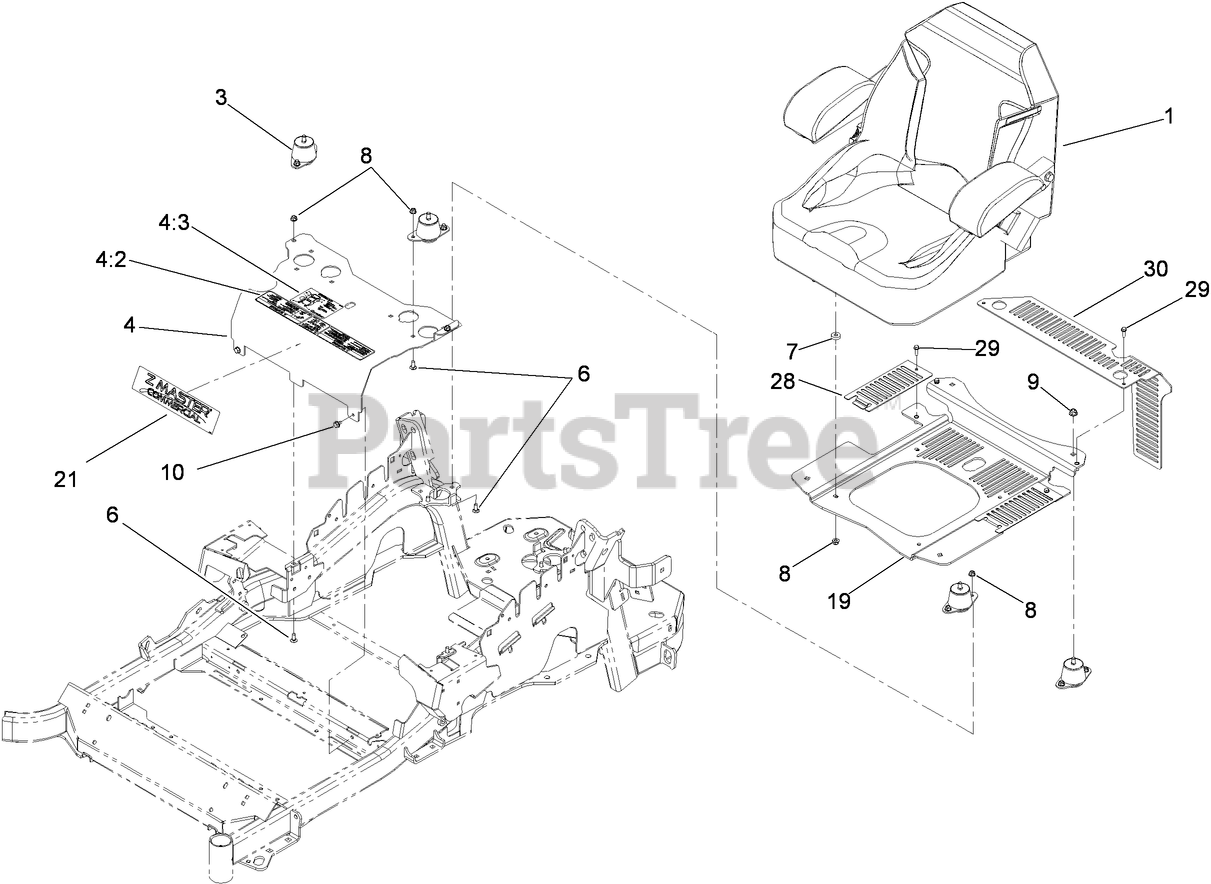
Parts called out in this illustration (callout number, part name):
1	SEAT-STANDARD
3	ISOLATOR-SEAT
4	MOUNT-SEAT
4:2	DECAL-CONSOLE
4:3	DECAL-SERVICE AID
6	SCREW-CARR
7	SPACER-PIN, MOUNTING
8	NUT-HF, NI
9	NUT-HF, NI
10	SCREW
19	SEAT BASE ASM
29	SCREW-HWH
